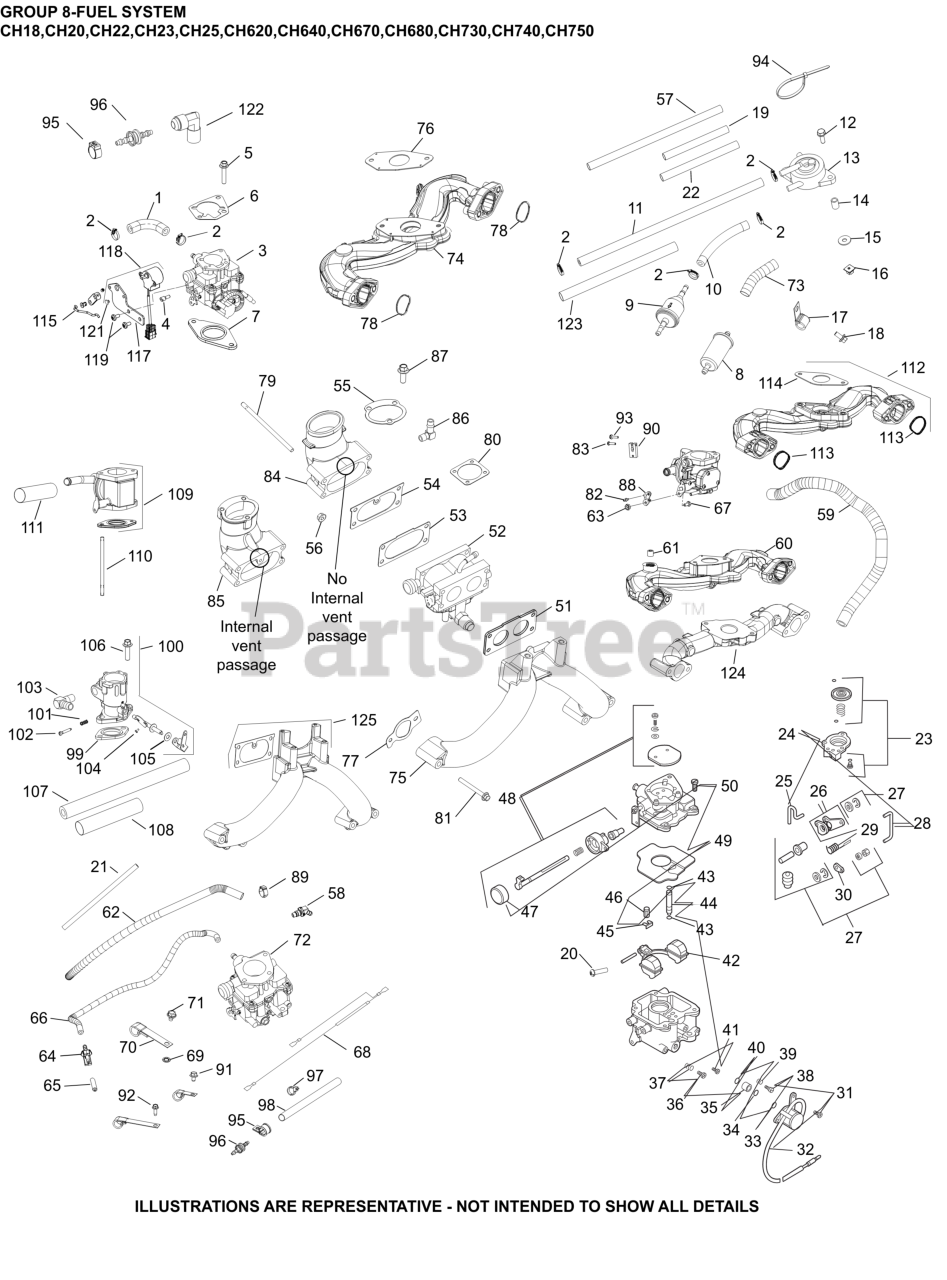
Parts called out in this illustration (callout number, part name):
1	HOSE,LW PERM.FUEL 24.00"-USE 25 111 81-S
2	CLAMP, HOSE (KM)-USE 25 237 31-S
5	SCREW, FLG M6X1.0X25
9	FILTER, FUEL
18	SCREW, FLG M6X1.0X12
23	KIT, REPAIR ACC PUMP
27	KIT, REPAIR-ACC PUMP SEAL
32	KIT, SOLENOID
42	KIT, REPAIR FLOAT
48	KIT, REPAIR CHOKE
64	CONNECTOR, EVAPORATIVE
65	CAP, MASKING
68	LEAD, GROUND
69	WASHER, INT TOOTH LOCK 1/4"
74	KIT, INTAKE MANIFOLD-USE 24 164 93-S
76	GASKET, CARBURETOR
78	O-RING, INTAKE PORT
NI	KIT, HIGH ALT (8,000+ FT)
NI	KIT, HIGH ALT (4000-8000 FT)
NI	KIT, REPAIR CARBURETOR
NI	KIT,CARB (KEIHIN)-(#24853306S)
